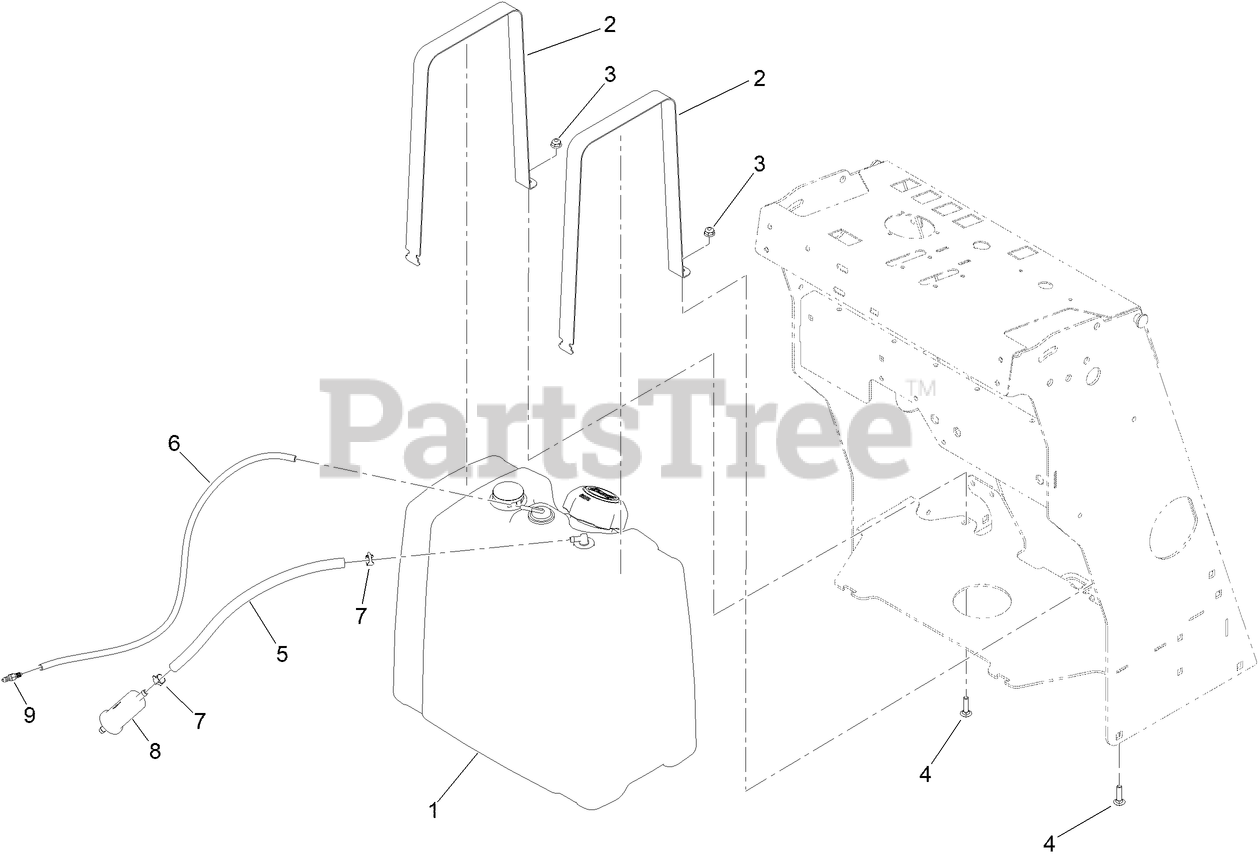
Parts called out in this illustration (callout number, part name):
1	ASM-TANK, FUEL
2	STRAP-TANK
3	Nut-Hex Flange
4	SCREW-CARR
5	HOSE-FUEL
6	HOSE-FUEL
7	CLAMP-HOSE
8	FILTER-FUEL
9	Fitting-STR
